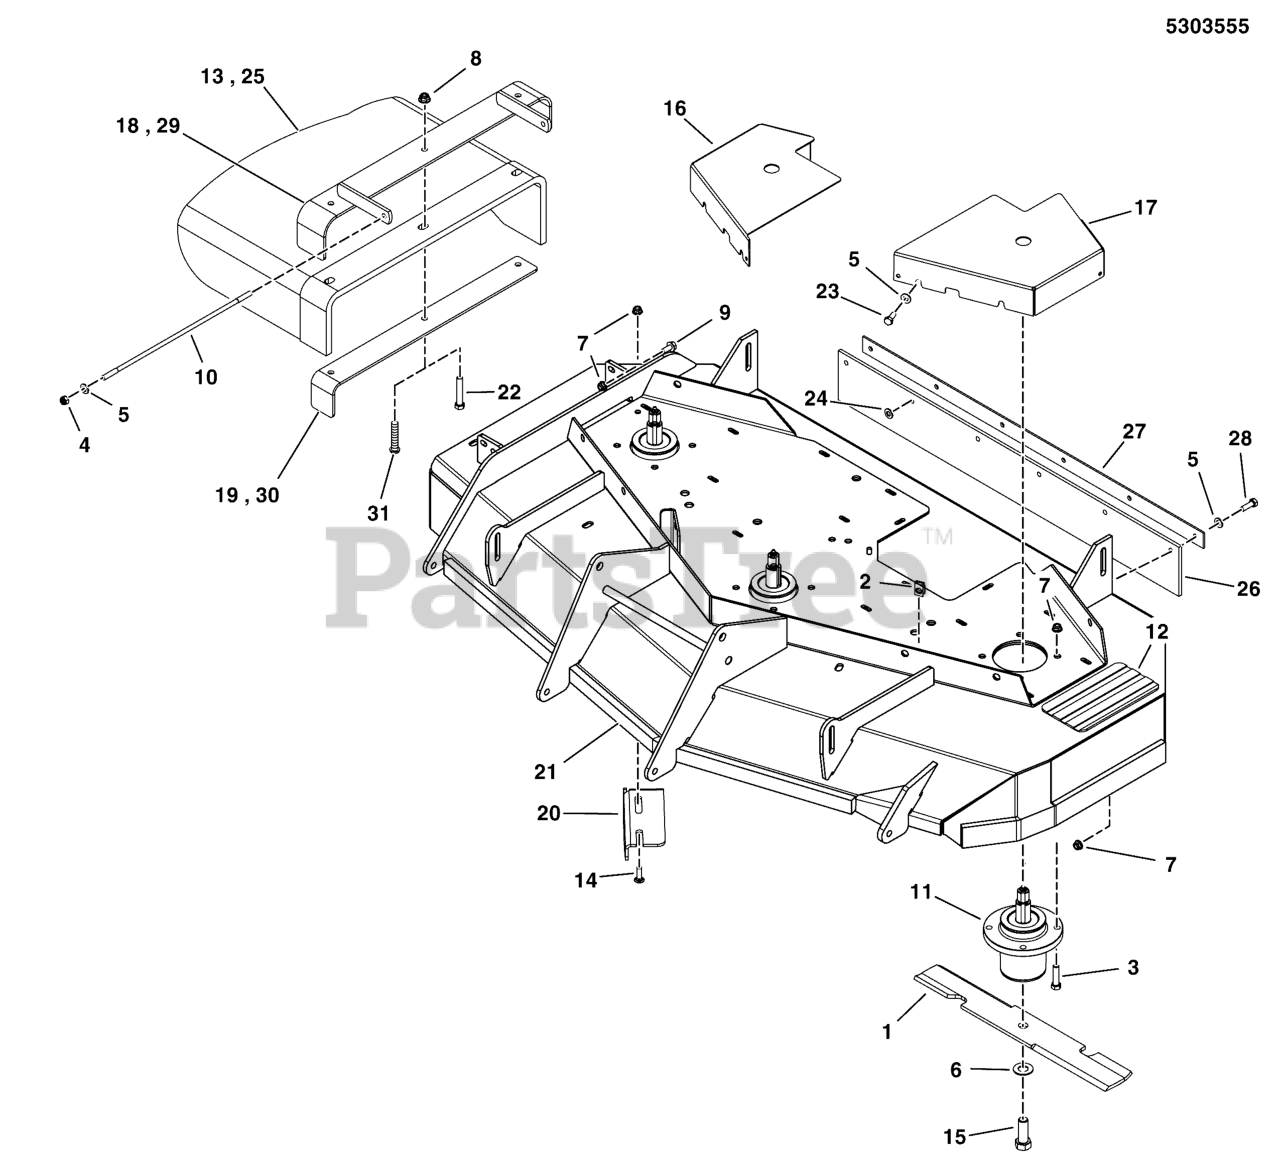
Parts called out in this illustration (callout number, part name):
1	BLADES, SET OF THREE (3); 16.25 X.25 X 2.5, 1 X 3.5
2	BODY CLIP, 5/16-18-7GA MATERIAL
3	BOLT, 5/16-18 X 1 1/4 FLANGE
4	NUT, 5/16-24 HEX NYLON LOCK
5	WASHER, 5/16" SAE
6	WASHER, 5/8 GRADE 8, YZ
7	NUT, 5/16-18 HEX NYLOCK FLANGE
8	NUT, 3/8-16 HEX NYLOCK FLANGE
9	BOLT, 5/16-18 X 3/4 GD5
10	ROD, 5/16 X 13.75, TBE, CZ
11	ASSM, SPINDLE, LOW PROFILE
12	SAFETY WALK, 4.00 X 7.50
13	CHUTE, DISCHARGE, RUBBER, 44/48/52
14	BOLT, 5/16-18 X 3/4, CARRIAGE
15	BOLT, 5/8-11 X 1-3/4 GD8
16	GUARD, 48 DECK - RH -RED
17	GUARD, 48 DECK - LH -RED
18	WELD, FRAME, CHUTE, 44/48/52 - BLK
19	SUPPORT, DISCHARGE CHUTE, 48/52 - BLK
20	PLATE, DEFLECTOR - BLK
21	DECK SHELL W/ DECALS, 48, S150XT (5411415D)
21	DECK SHELL W/ DECALS, 48, S150XT-DOM (5413100D)
22	BOLT, 3/8-16 X 1-1/2" GD5 CZ
23	BOLT, 5/16-18 X 1 GD5 YZ
24	5/16 PUSH-ON NUT RETAINER, STL, CZ
25	CHUTE, RUBBER DISCHARGE
26	FLAP, RUBBER, 48"
27	PLATE, SUPPORT, 48 - BLK
28	BOLT, 5/16-18 X 1 GD5 YZ
29	WELD, MOUNT, DISCHARGE CHUTE - BLK
30	SUPPORT, DISCHARGE CHUTE - BLK
31	BOLT, 3/8-16 X 1-1/2, CARRIAGE, GD5, CZ
